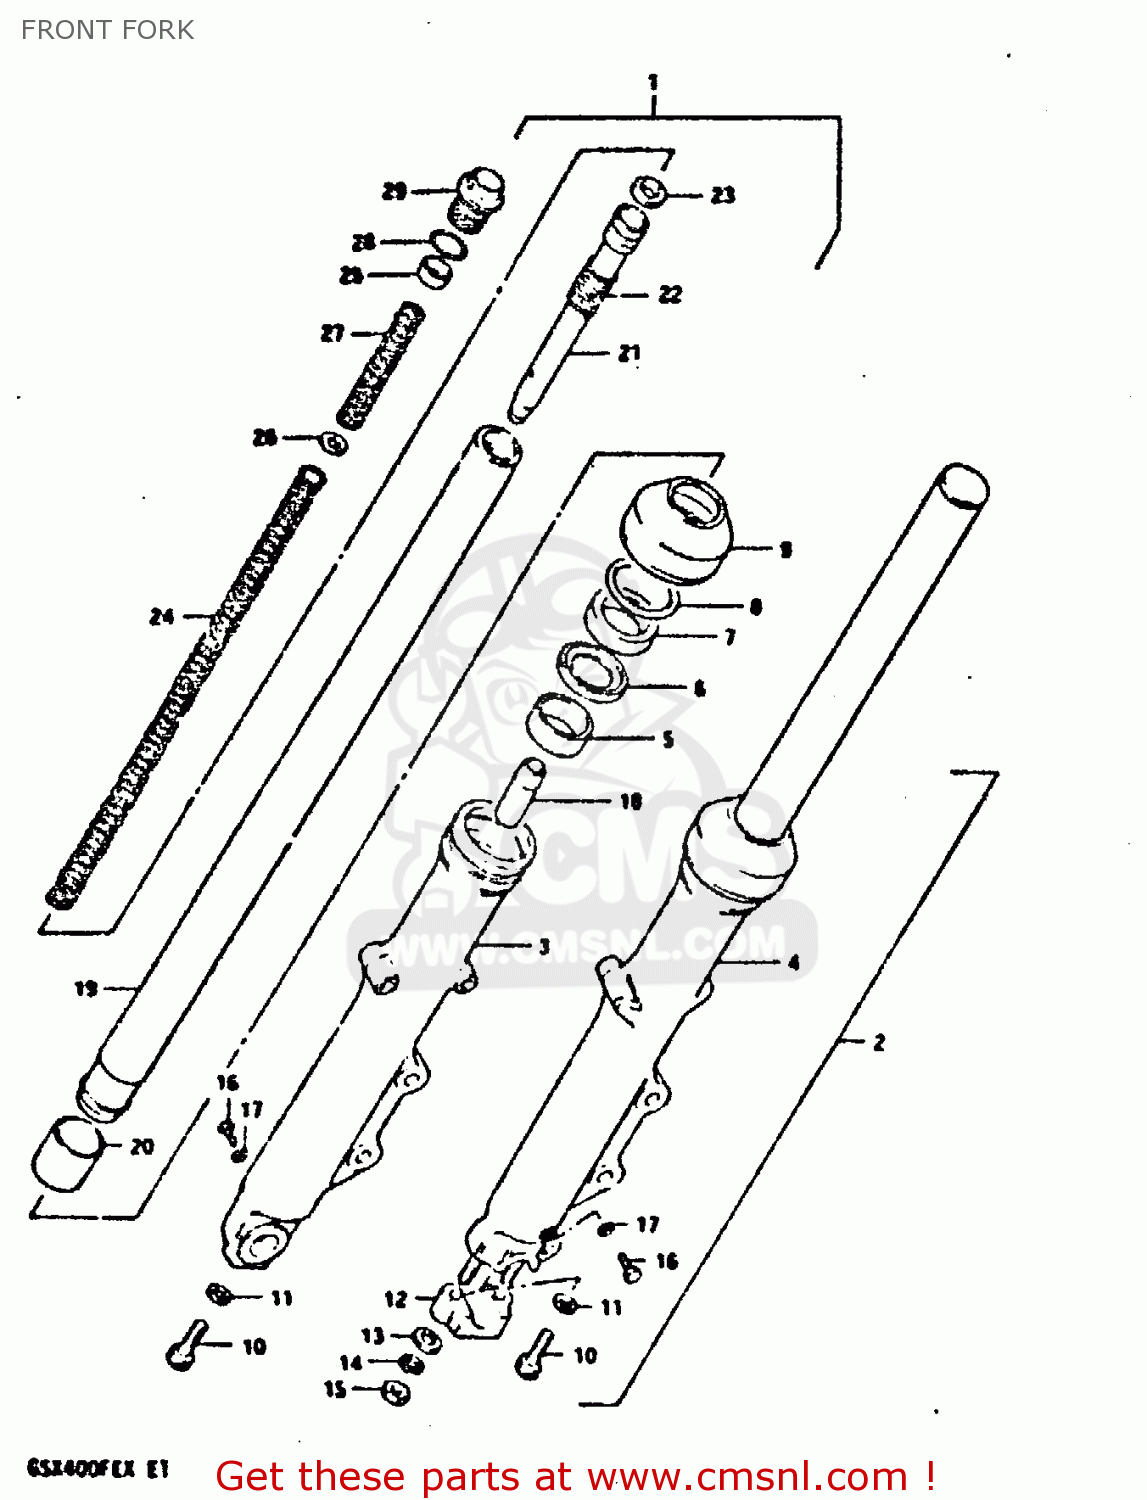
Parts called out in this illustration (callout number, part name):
1	DAMPER ASSY, RH
2	DAMPER ASSY, LH
3	OUTER TUBE RH
4	OUTER TUBE LH
5	BUSH,GUIDE
6	SPACER,OIL SEAL
7	OIL SEAL,FRONT FORK
8	CIRCLIP,FORK OIL SEAL
9	DUST SEAL
10	BOLT(8X27)
11	GASKET (NAS)
12	HOLDER,AXLE
13	WASHER
14	LOCK WASHER
15	NUT
16	BOLT(6X8)
17	GASKET
18	PIECE,OIL LOCK
19	INNER TUBE
20	BUSH
21	CYLINDER
22	SPRING,REBOUND
23	RING,PISTON
24	SPRING B
25	SPACER,FRONT FORK SPRING
26	SEAT,SPRING
27	SPRING A
28	O RING
29	BOLT
